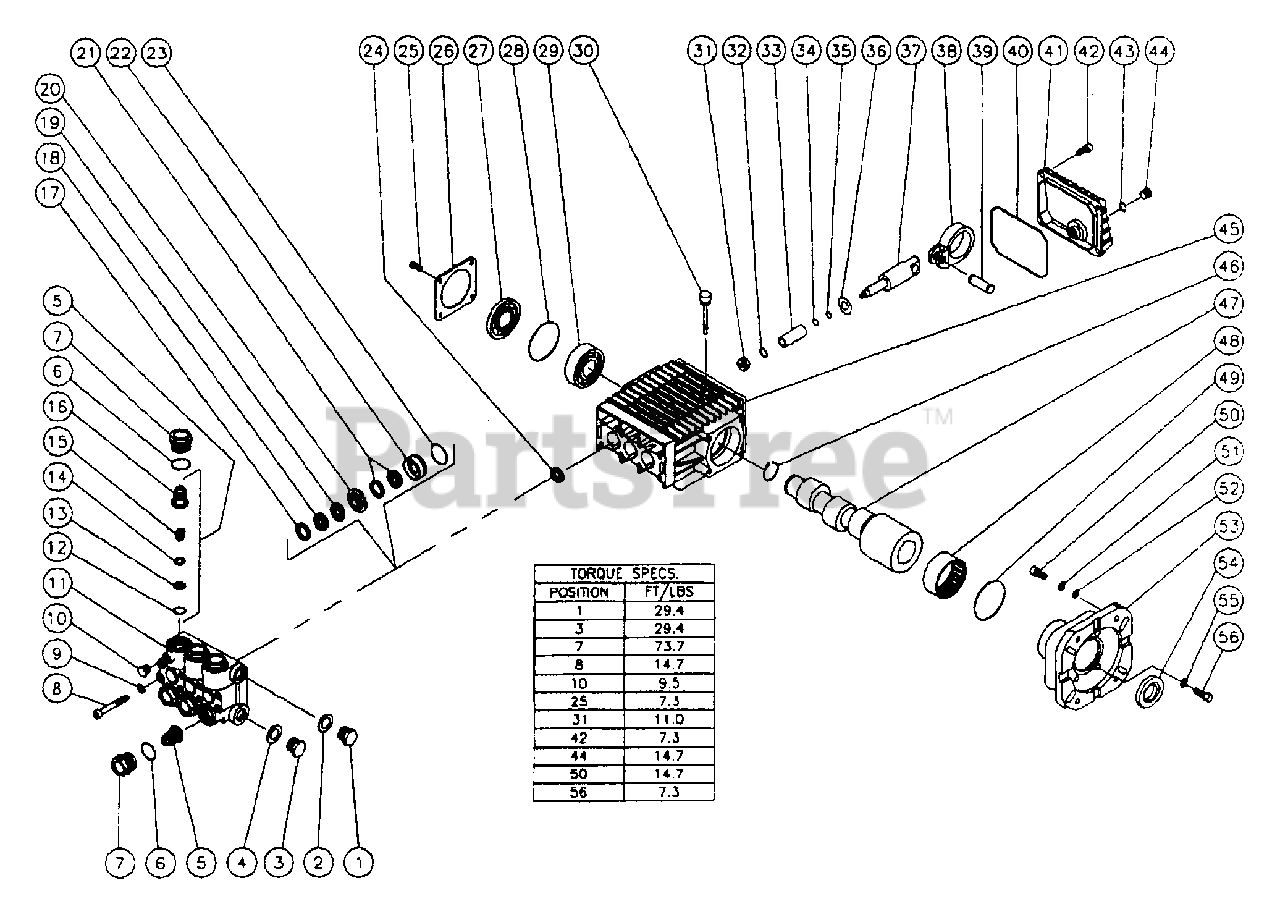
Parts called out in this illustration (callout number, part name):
1	Plug
3	Plug
5	Valve Assy.
7	Valve Plug
8	Bolt
9	Lockwasher
10	Plug
11	Pump Manifold
12	O-ring
13	Valve Seat
14	Valve Plate
15	Valve Spring
16	Valve Cage
17	Head Ring
18	V-Packing
19	Stop Ring Packing
20	Intermediate Ring
21	Low Pressure Seal
22	Packing Retainer
25	Bolt
26	Retainer
27	Oil Level Indicator
29	Ball Bearing
30	Oil Dipstick
31	Nut
35	Back-up Ring
36	Flinger Washer
37	Piston Guide
38	Connecting Rod
39	Pin/Connecting Rod
41	Crankcase cover
42	Bolt
44	Plug
45	Crankcase
46	Snap Ring
47	Crankshaft
48	Bearing/Needle
50	Bolt
51	Lockwasher
54	Oil Seal
55	Lockwasher
56	Bolt
